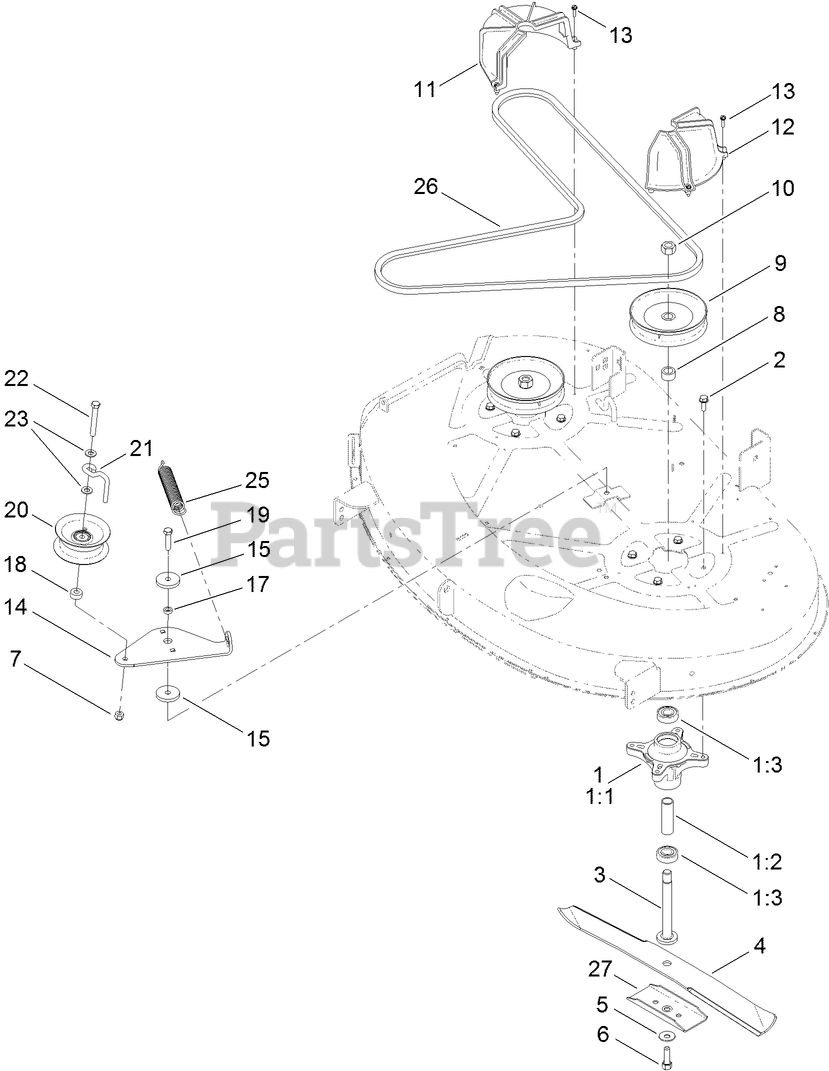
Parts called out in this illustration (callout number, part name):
1:2	SPACER
2	SCREW-TAPTITE
3	SHAFT-SPINDLE
5	WASHER-BELLEVILLE
6	SCREW-HH
7	NUT-HF, NI
8	SPACER-PULLEY
9	PULLEY
10	NUT-HEX
11	GUIDE-BELT, RH
12	GUIDE-BELT, LH
13	SCREW-SHWH, THREAD FORMING
14	ARM-IDLER
15	WASHER-PLAIN
17	SPACER
18	SPACER
19	SCREW-HH
21	GUIDE-IDLER, BELT
22	SCREW-HH
23	WASHER-FLAT
25	SPRING-EXTENSION
27	STIFFENER-BLADE
